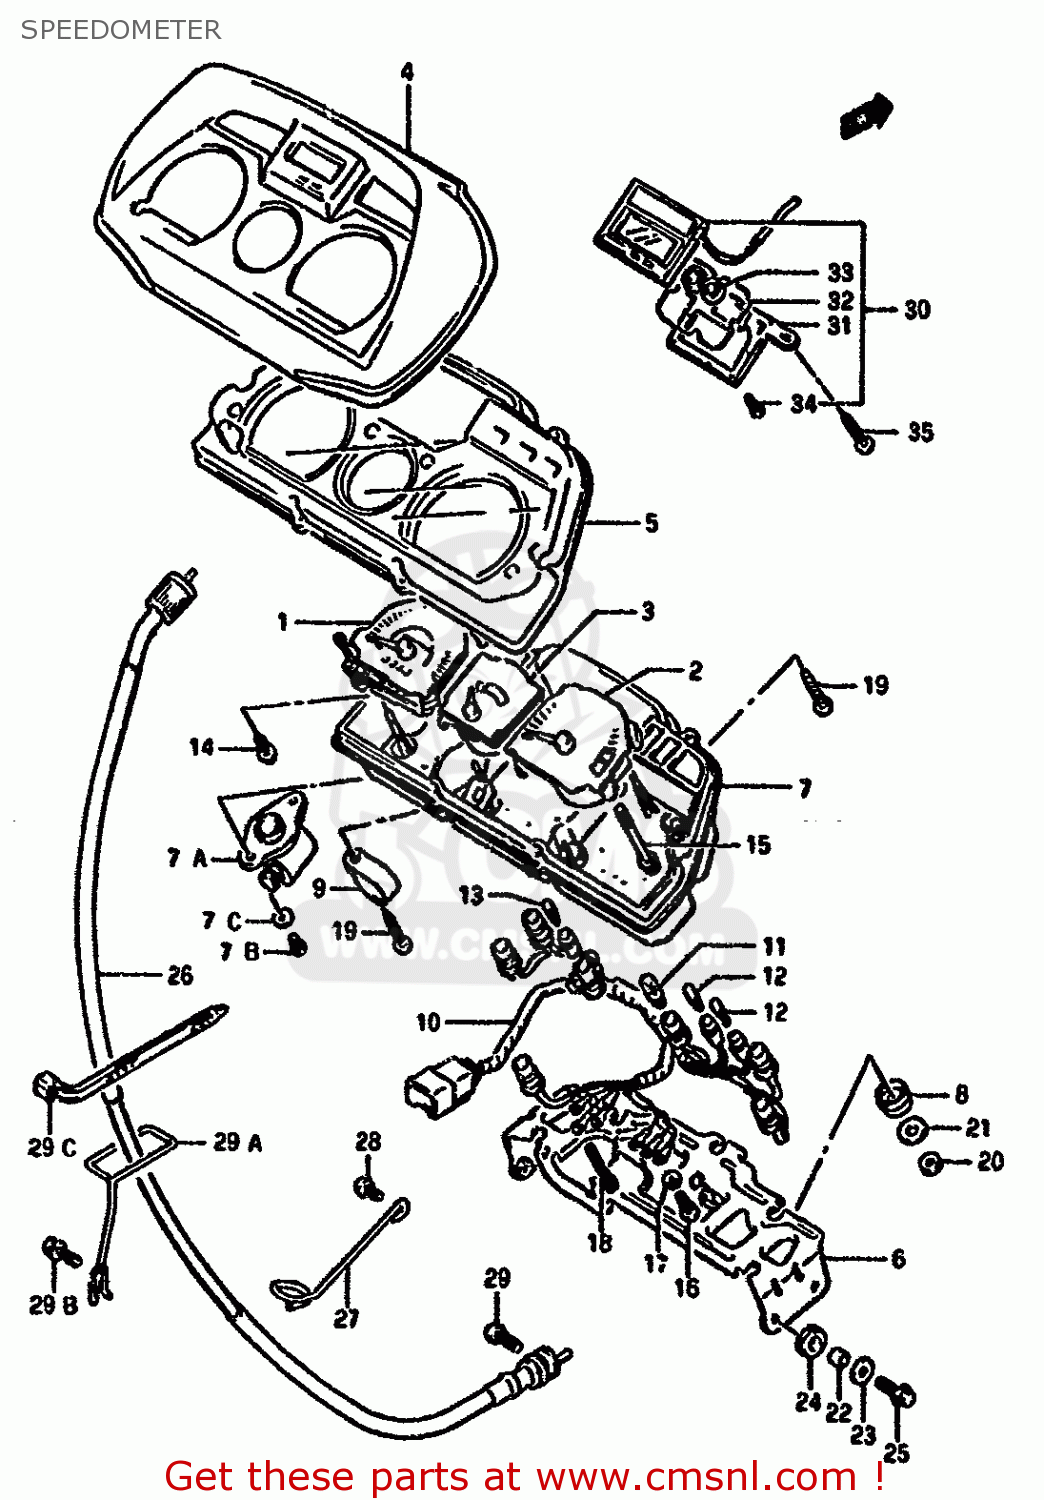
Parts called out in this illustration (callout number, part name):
1	SPEEDOMETER
2	TACHOMETER
3	METER,FUEL
4	VISOR
5	GLASS ASSEMBLY
6	BRACKET,METER
7	CASE
7A	GEAR BOX
7B	SCREW
7C	WASHER (4X16X1.2)
8	CUSHION
9	CLAMP,METER
10	SOCKET,METER
11	BULB(12V3.4W,T10)
12	BULB(12V3W,T6.5)
13	BULB(12V1.7W,T6.5)
14	SCREW
15	SCREW (4X36)
16	SCREW
17	LOCK WASHER
18	SCREW(3X22)
19	SCREW
20	NUT 5MM
21	WASHER (5.5X16X1.2)
22	SPACER (6X9X8)
23	WASHER
24	CUSHION
25	BOLT 6X20
26	CABLE ASSY,SPEEDOMETER
27	CLAMP,SPEEDOMETER CABLE
28	BOLT
29	SCREW
29A	GUIDE,SPEEDOMETER CABLE
29B	BOLT
29C	CLAMP(L:125)
30	CLOCK ASSEMBLY
31	CASE,LOWER
32	GASKET (NAS)
33	BATTERY,LITHIUM
34	SCREW,TAPPING
35	SCREW(3X16)
